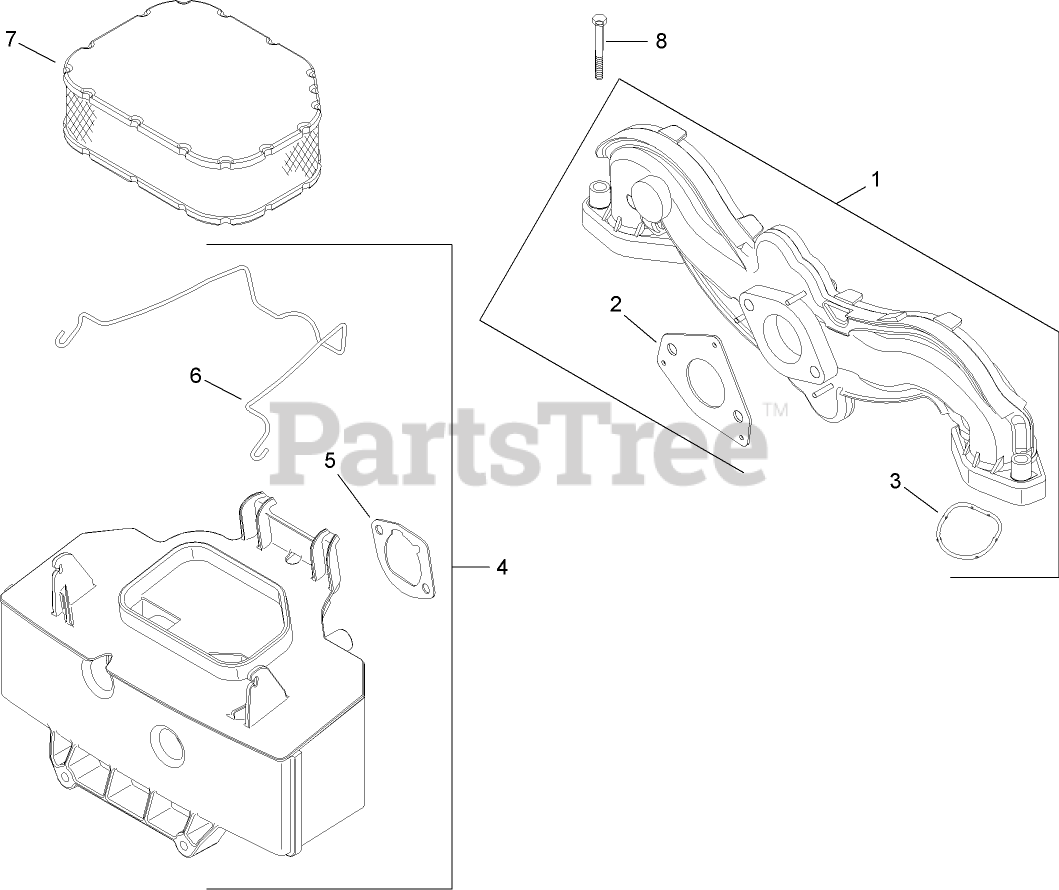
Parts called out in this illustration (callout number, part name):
1	Manifold-Intake (Includes 2-3)
2	GASKET-CARBURETOR
3	O-RING
4	Base-Air Cleaner (Includes 5-6)
5	GASKET-BASE, AIR CLEANER
6	LATCH-ELEMENT, AIR CLEANER
7	FILTER-AIR
8	SCREW-FLANGE (M6X1.0X40)
